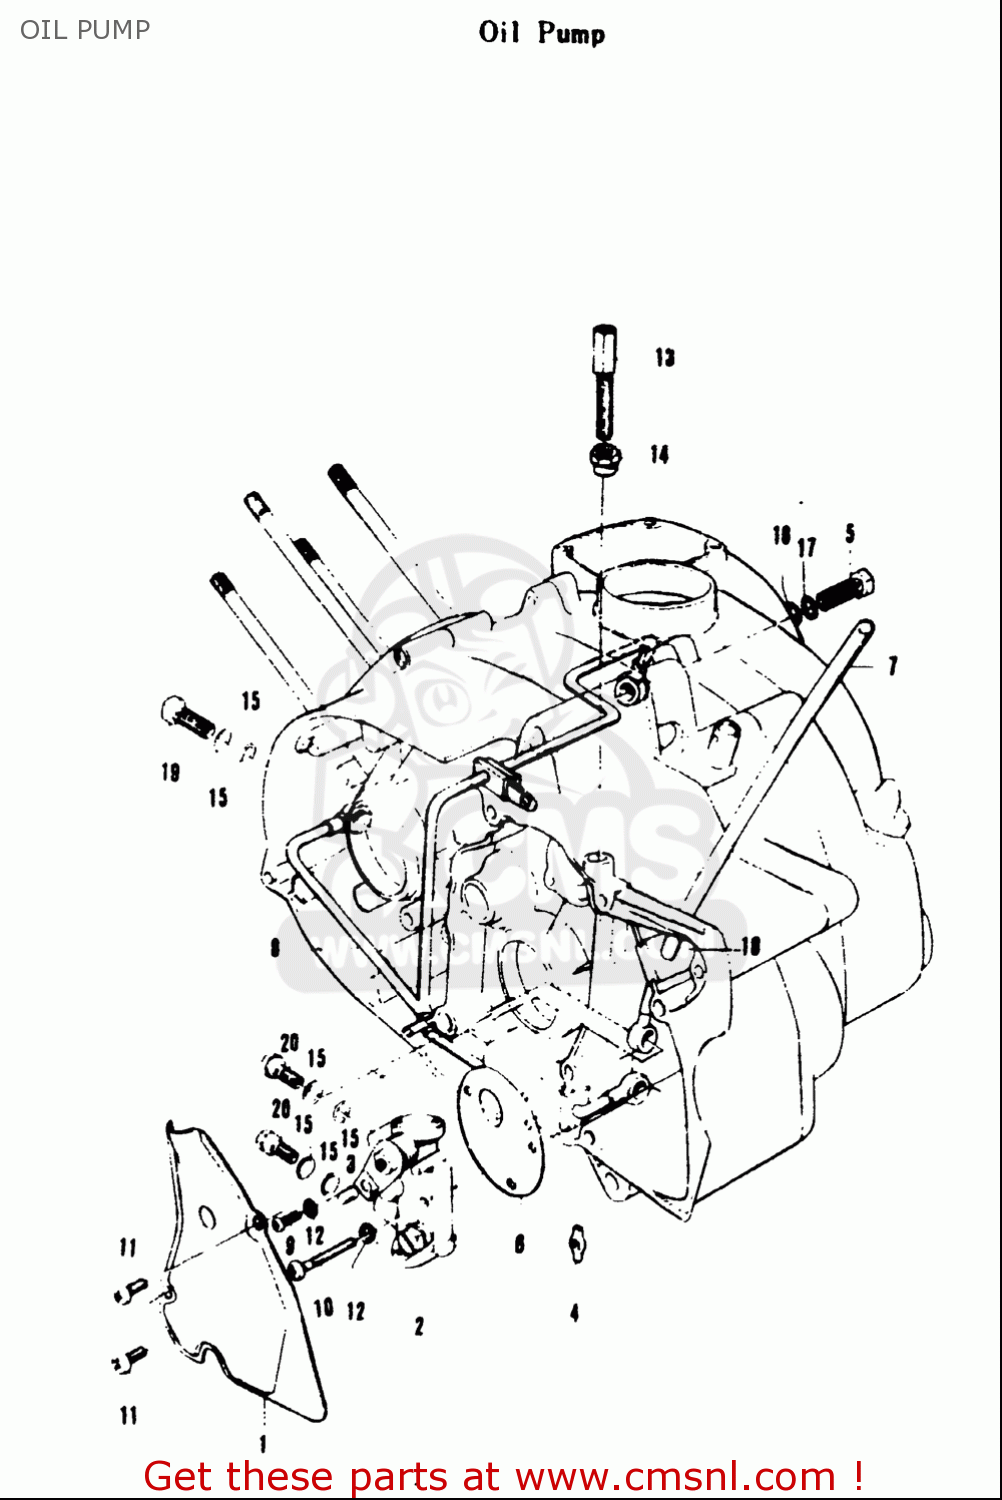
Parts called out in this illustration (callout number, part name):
3	TERMINAL,CABLE
4	PIECE,OIL PUMP DRIVE
6	GASKET,OIL PUMP (NAS)
9	SCREW
12	WASHER,LOCK
15	GASKET(6.2X11X1).2 (NAS)
16	GASKET(10X16X3) (NAS)
17	O RING(D:1.3,ID:7.6)
18	GROMMET
19	UNION BOLT
